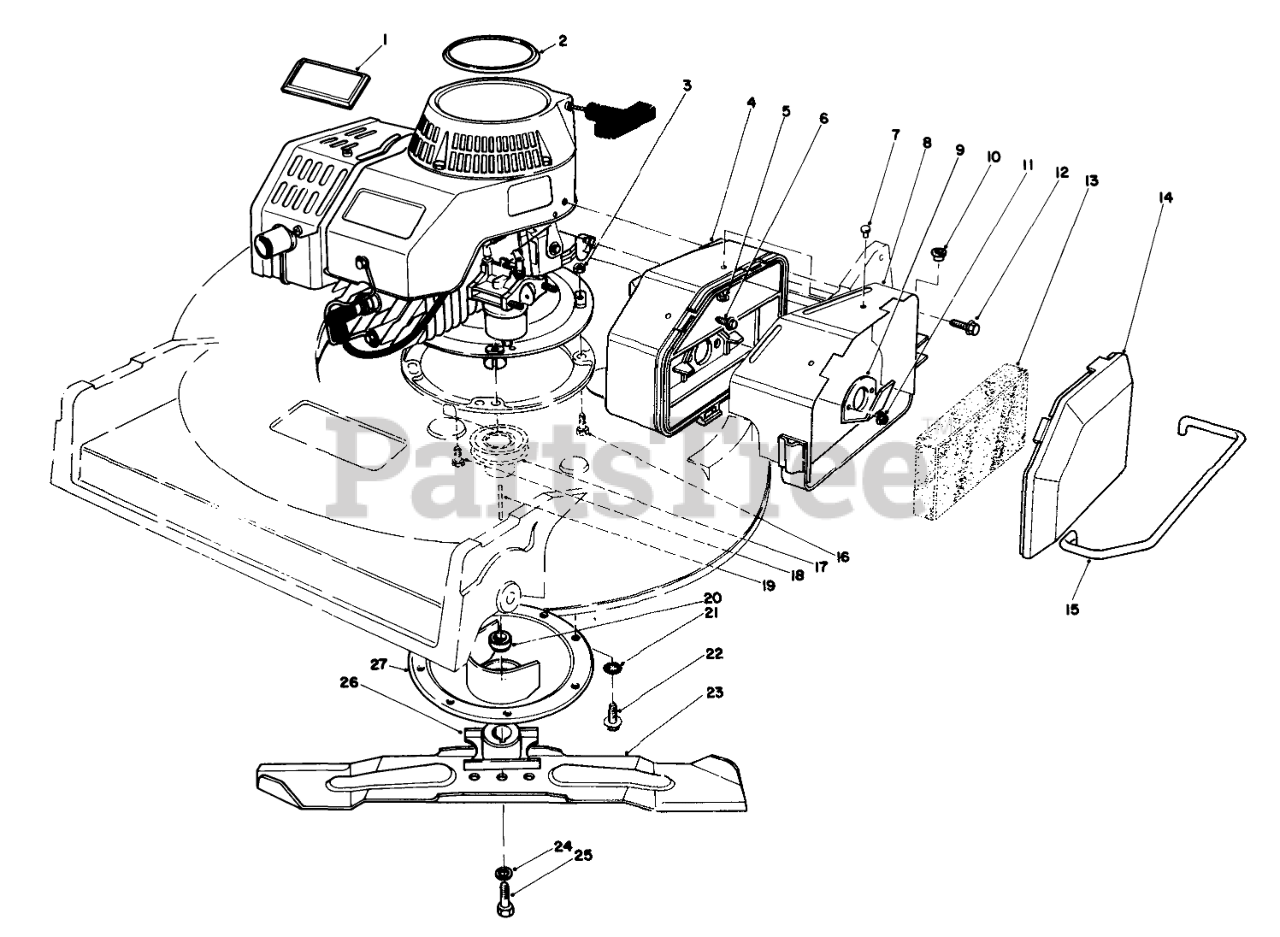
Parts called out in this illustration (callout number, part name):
1	Plate-Logo
2	Plate-Engine Logo
3	NUT-JAM
4	Air Cleaner Assembly (Incl. Ref. #5, 7, 8)
5	WASHER-FLAT
6	HEX FL HD M.6X1.0X25MM
7	RIVET-POP
8	AIR CLEANER COVER WA
9	SPIT BACK DEFLECTOR
10	5/16 ID BSHG
11	NUT-LOCK
12	SCREW-HHF
13	FILTER
14	AIR CLEANER COVER
15	AIR CLEANER GUARD
16	SCREW-HH
17	PULLEY-DRIVER
18	SCREW-HH
19	KEY-SQUARE
20	SPACER-BLADE RETAINER
21	WASHER-LOCK, INTERNAL
22	SCREW-HWHTF
23	BLADE-21in
24	WASHER-LOCK
25	SCREW-BLADE
26	RETAINER-BLADE
27	PROTECTOR-CRANKSHAFT
